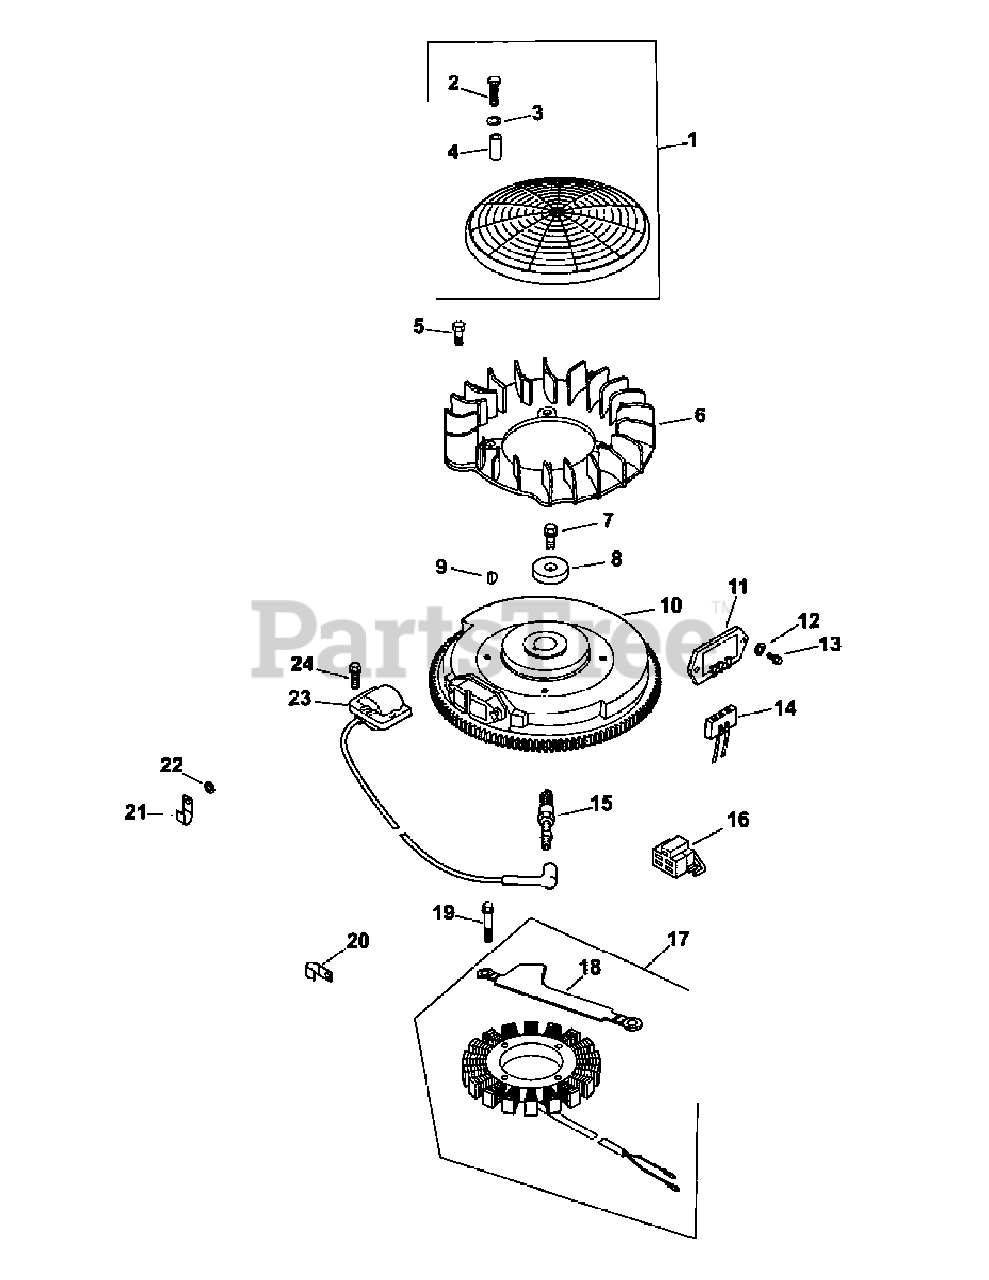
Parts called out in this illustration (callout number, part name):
1	Grass Screen Kit
2	Hex Head Screw (M4 x .7 x 25)
3	Plain Washer
5	Shoulder Bolt (M6 x 1.0 x 16)
6	Fan
7	Hex Flange Screw (M10 x 1.5 x 46)
8	Plain Washer (3/8")
10	Flywheel
11	Regulator - Rectifier
12	Plain Washer (3/16")
13	Phillips Head Screw (11-16 x 7/8")
14	Connector (3 Contact)
15	Spark Plug
16	Connector (5 Contact)
17	15 amp Stator Kit
18	Stator Wire Bracket
19	Hex Cap Screw (M5 x .8 x 25)
20	Cable Clip
22	Plain Washer (1/4")
23	Ignition Module
24	Hex Flange Screw (M5 x .8 x 20)
